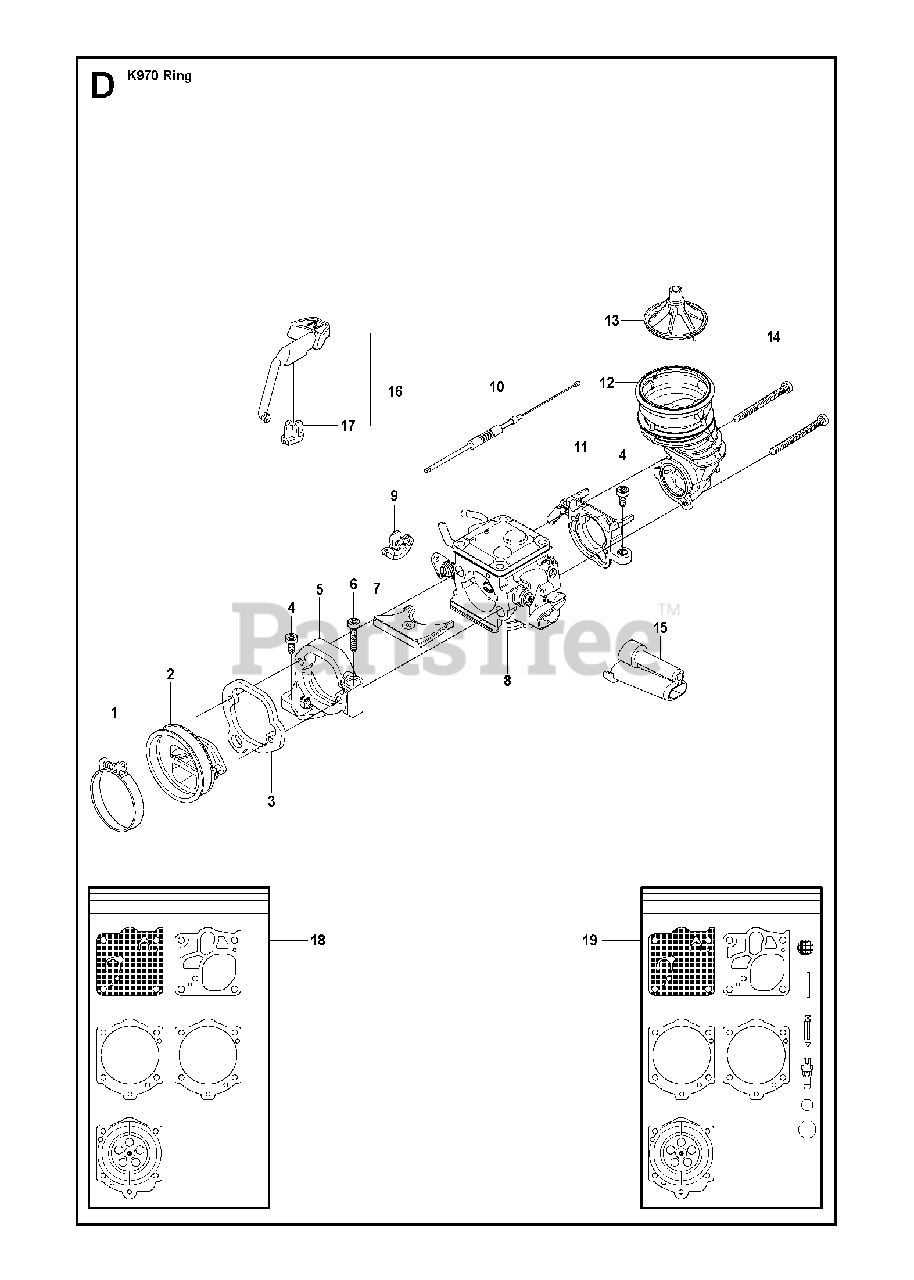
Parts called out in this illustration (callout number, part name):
1	HOSE CLAMP
4	SCREW ITXSCM
6	SCREW ITXSCM
8	CARBURETTORWalbro RWJ-5
10	THROTTLE CABLE ASSY
11	FLANGE INLET PIPE
14	SCREW ITXSCM
15	CHISEL GUIDE
16	CHOKEIncl. 17
17	WEAR PROTECTION
18	GASKET KITWalbro RWJ-5
19	REPAIR KITWalbro RWJ-5
